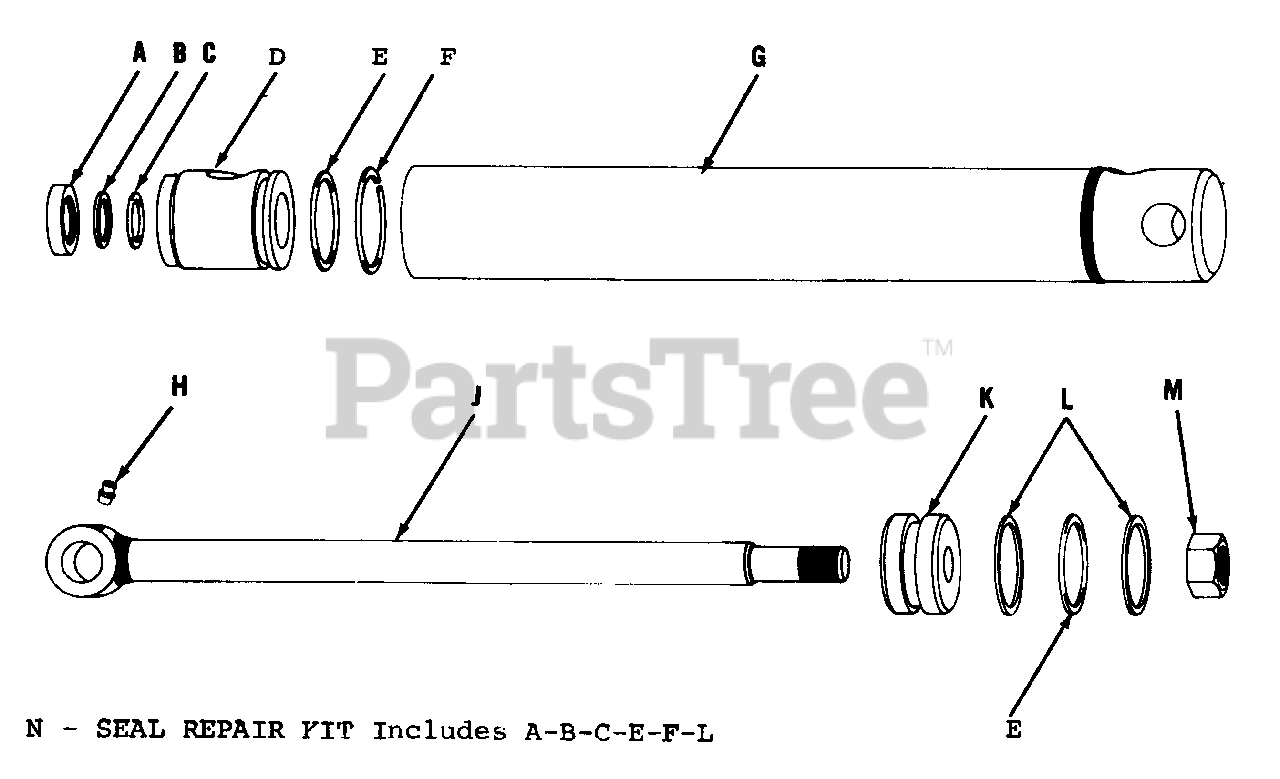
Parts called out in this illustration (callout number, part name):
A	Ring Wiper
B	Back-Up Washer
D	Cylinder Head
F	Retainer Ring
G	Cylinder Tube Ass'y.
H	Grease Fitting
J	Piston Rod Ass'y.
L	Back-Up Washer
M	Full Lock Hex. Nut, 5/8"-18 N.F.
N	Major Seal Repair Kit
